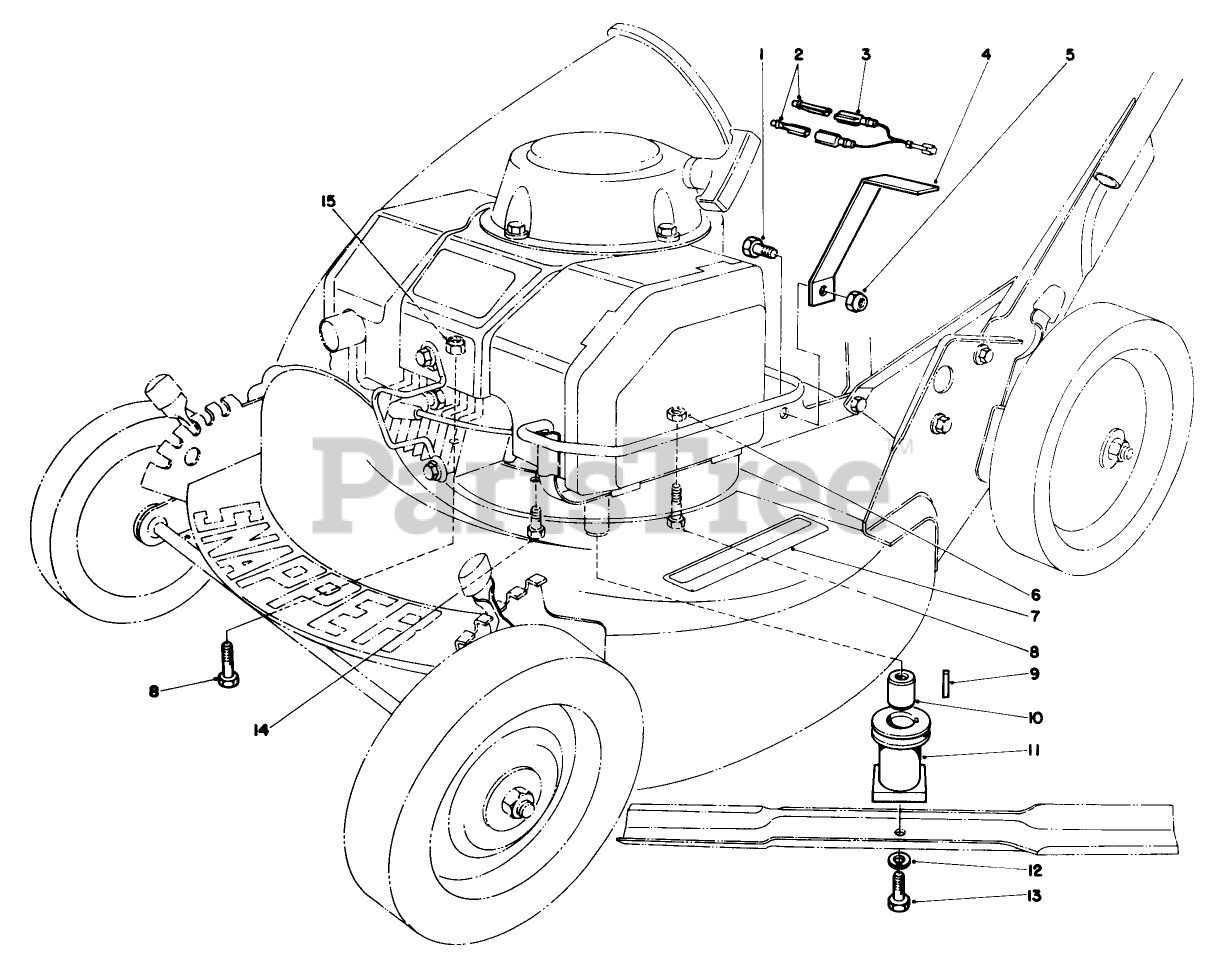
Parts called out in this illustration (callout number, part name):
1	SCREW-HH
2	FEMALE SLIDE TERMINAL
3	WIRE ASY
4	LOWER TANK MOUNT
5	NUT-LOCK, NI
6	NUT-JAM
7	CAUTION DECAL
8	SCREW-HH
9	KEY-SQUARE
10	Spacer-Pulley
11	BLADE RETAINER W.A.
12	WASHER-LOCK
13	SCREW-BLADE
14	SCREW-HH
15	NUT-LOCK, NI
